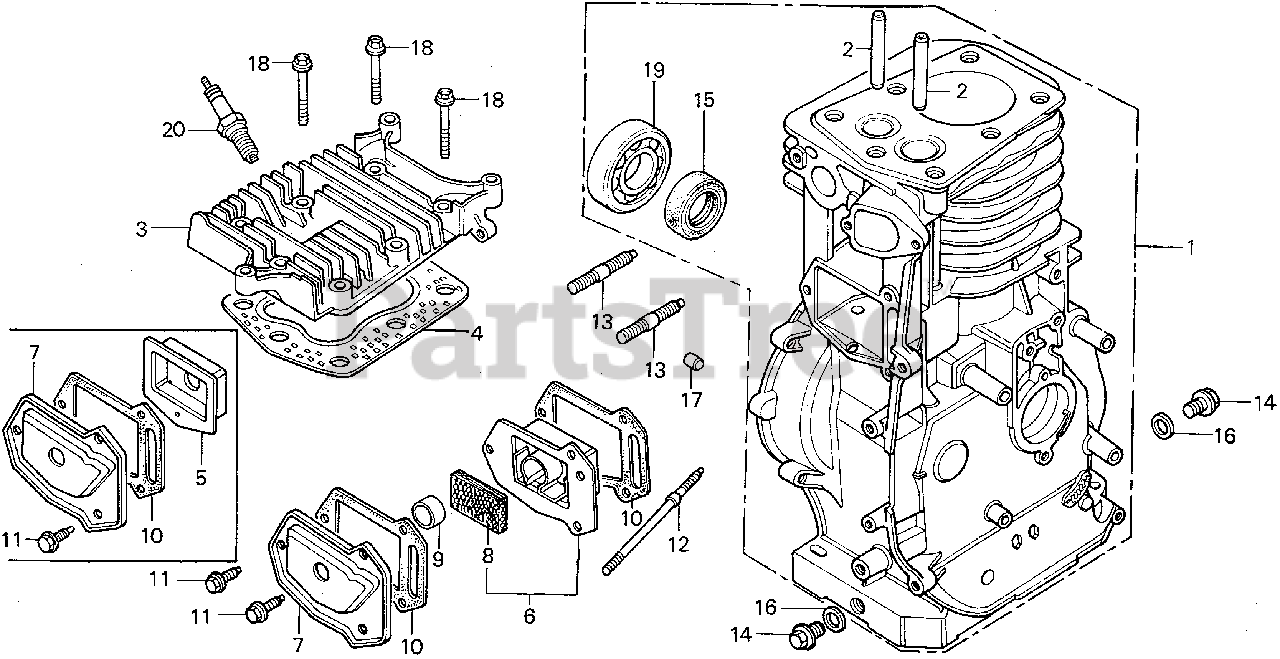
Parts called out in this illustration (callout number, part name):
1	CYLINDER ASSY.
2	GUIDE, VALVE (OVER SIZE)
3	CYLINDER HEAD
4	GASKET, CYLINDER HEAD
5	CASE, BREATHER
6	CASE, BREATHER
7	COVER, TAPPET ROOM
8	FILTER, BREATHER
9	SEAL, BREATHER
10	GASKET, TAPPET COVER
11	BOLT, FLANGE (6X12) (CT200)
12	BOLT, STUD (6X95)
13	BOLT, STUD (8X35)
14	BOLT, DRAIN PLUG (12X15)
15	OIL SEAL (25X41X6)
16	WASHER, DRAIN PLUG (12MM)
17	PIN, DOWEL (8X14)
18	BOLT, FLANGE (8X45)
19	BEARING, RADIAL BALL (6205)
20	SPARK PLUG (BR-4HS) (NGK)
20	SPARK PLUG (W14FR-U)
